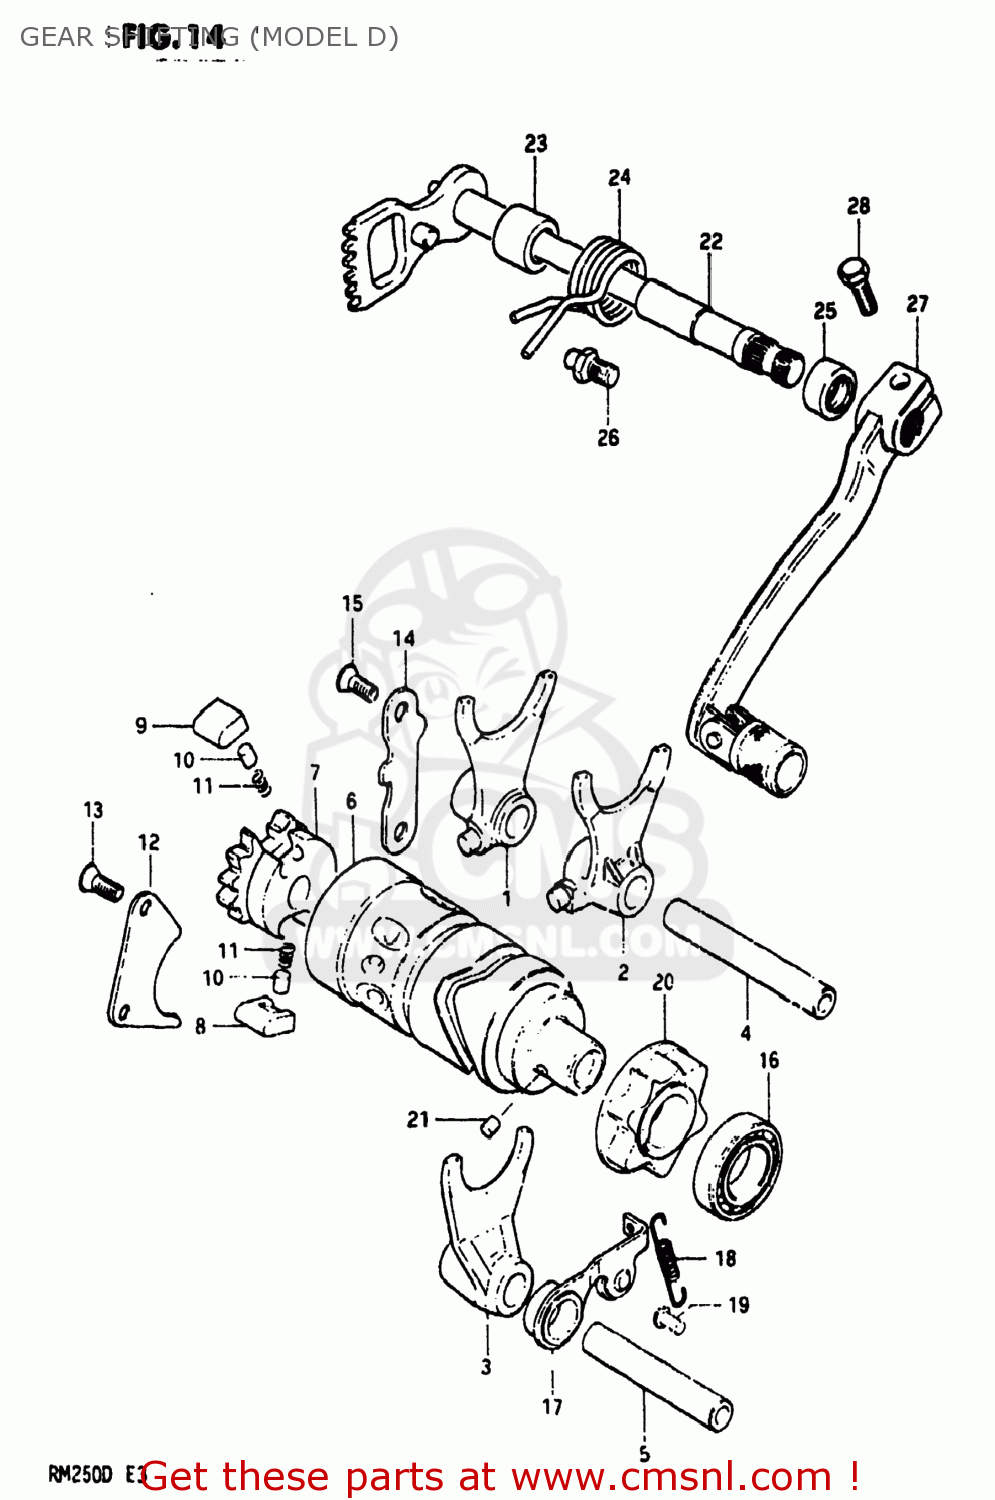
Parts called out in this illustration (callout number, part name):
1	FORK,GEAR SHIFT NO.1
2	FORK,GEAR SHIFT NO.2
3	FORK,GEAR SHIFT NO.3
4	SHAFT,GEAR SHIFT FORK
5	SHAFT,GEAR SHIFT FORK
6	CAM,GEAR SHIFT
7	RETAINER,GEAR SHIFT CAM
8	PAWL,GEAR SHIFT NO.1
9	PAWL,GEAR SHIFT NO.2
10	PIN(5X8)
11	SPRING
12	LIFTER,GEAR SHIFT PAWL
13	SCREW
14	GUIDE,GEAR SHIFTING CABLE
15	SCREW
16	BEARING
17	STOPPER,GEAR SHIFTING
18	SPRING
19	RIVET
20	PLATE,GEAR SHIFT CAM STOPPER
21	PIN 4X6
22	SHAFT,GEAR SHIFT
23	SPACER(12X20X15.3)
24	SPRING
25	OIL SEAL
26	STOPPER,GEAR SHIFT CAM
27	LEVER ASSEMBLY,GEAR SHIFTING
28	BOLT
